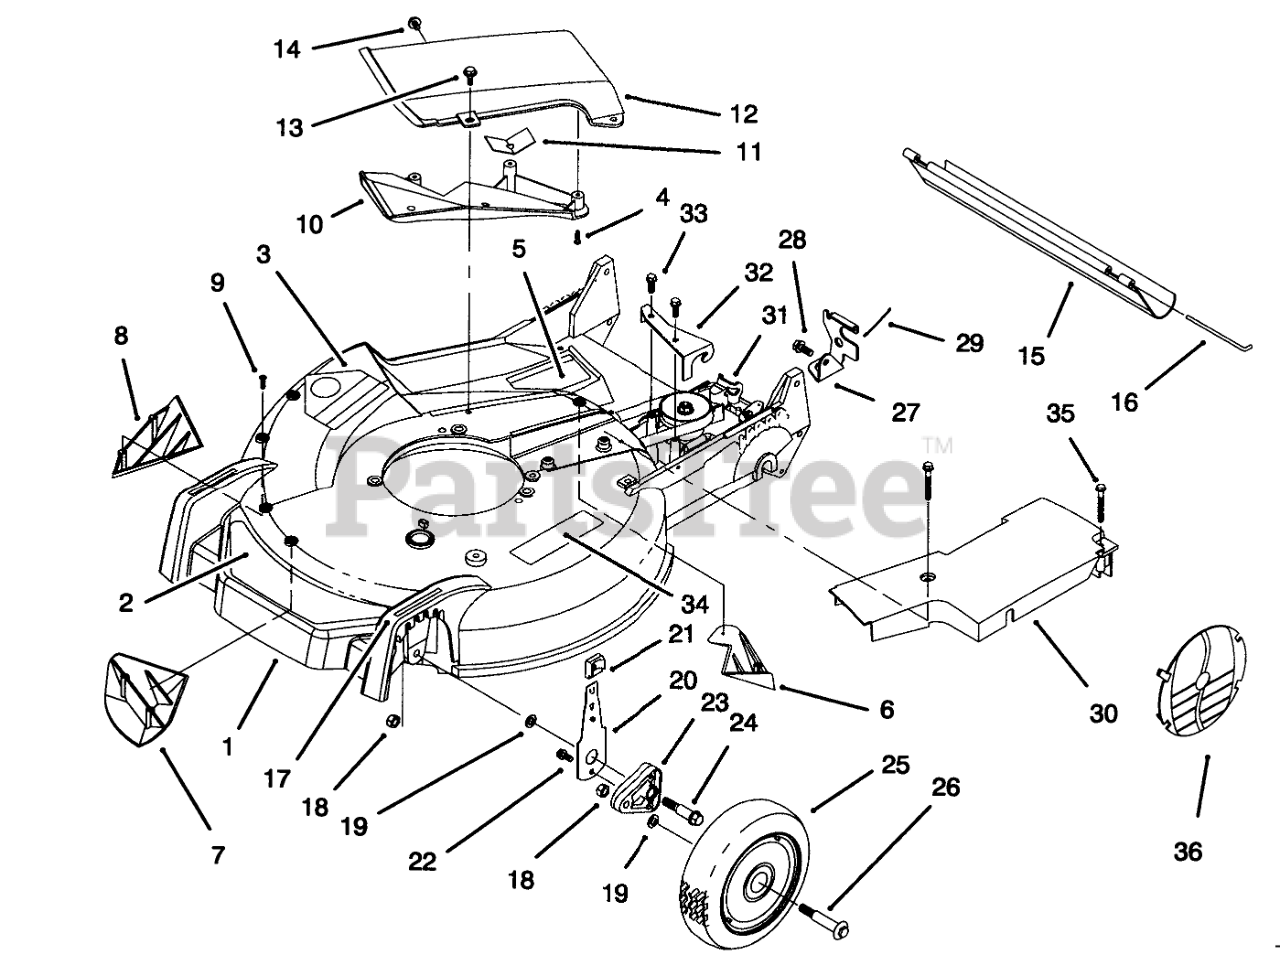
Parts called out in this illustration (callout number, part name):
1	Housing 21" (Incl. Ref. #3, 5-9 pg. 1, 34 pg. 2)
2	DECAL - DECK
3	DECAL-DANGER
4	Screw-PPH
5	DECAL - DANGER
6	KICKER-REAR
7	KICKER-FRONT
8	KICKER-RH
9	SCREW-PPH
10	Deflector-Recycler
11	Guard-Cover
12	Cover-Recycler (Incl. Ref. #4, 10, & 11)
13	SCREW-HWH
14	SCREW AND WASHER ASM
15	SHIELD-TRAILING
16	ROD-SHIELD
17	DECAL - HOC
18	NUT-LOCK
19	WASHER
20	FRONT SPRING ARM ASM
21	KNOB-ARM
22	SCREW-HWH
23	ARM-PIVOT, FRONT
24	BOLT-SHOULDER
25	WHEEL AND TIRE ASM
26	BOLT-WHEEL
27	Bracket-Adj. Trac
28	SCREW-HWHTF
29	RETAINER-CABLE
30	BELT COVER
31	GEARCASE ASM
32	Bracket-Guide
33	SCREW-HWHTF
34	DECAL-WARNING
35	SCREW-HHFTF
36	WHEEL COVER
